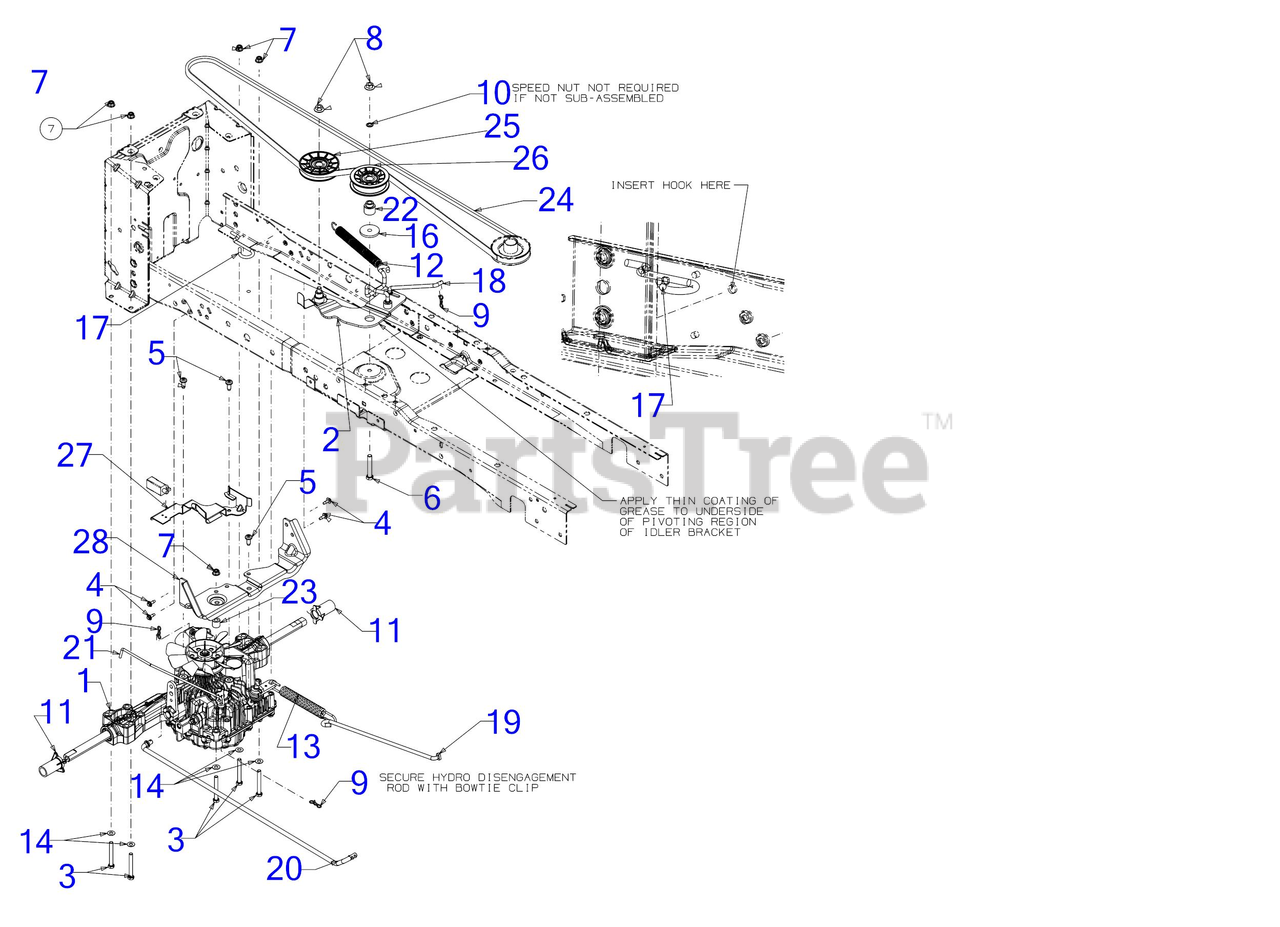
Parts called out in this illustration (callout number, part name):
1	TRANSMISSION ASSEMBLY
2	IDLER BRACKET ASSEMBLY
3	SCREW 5/16-18 x 2.5 GR 5
4	SCREW M6-1 x .625
5	SCREW 5/16-18 x .750
6	SCREW 3/8-16 x 2.25 GR5
7	FLANGE LOCK NUT 5/16-18
8	FLANGE LOCK NUT
9	BOW TIE COTTER PIN 1/4-5/16
11	AXLE SLEEVE .765 ID x 2.11 LG
12	EXTENSION SPRING .790 DIA x 8.41
13	EXTENSION SPRING 0.90 DIA x 8.14
14	FLAT WASHER
16	SHOULDER SPACER
17	DECK SPRING HOOK
18	IDLER BRACKET ROD
19	BRAKE ROD
20	HYDRO CONTROL ROD
21	HYDRO DISENGAGEMENT ROD
22	SHOULDER SPACER
23	SPACER .34 x .75 x .63 LG
24	V-BELT A SEC x 91.10
25	V-IDLER PULLEY 3.56 OD
26	FLAT IDLER PULLEY 3.00 OD
27	TRANSMISSON MOUNTING BRACKET
